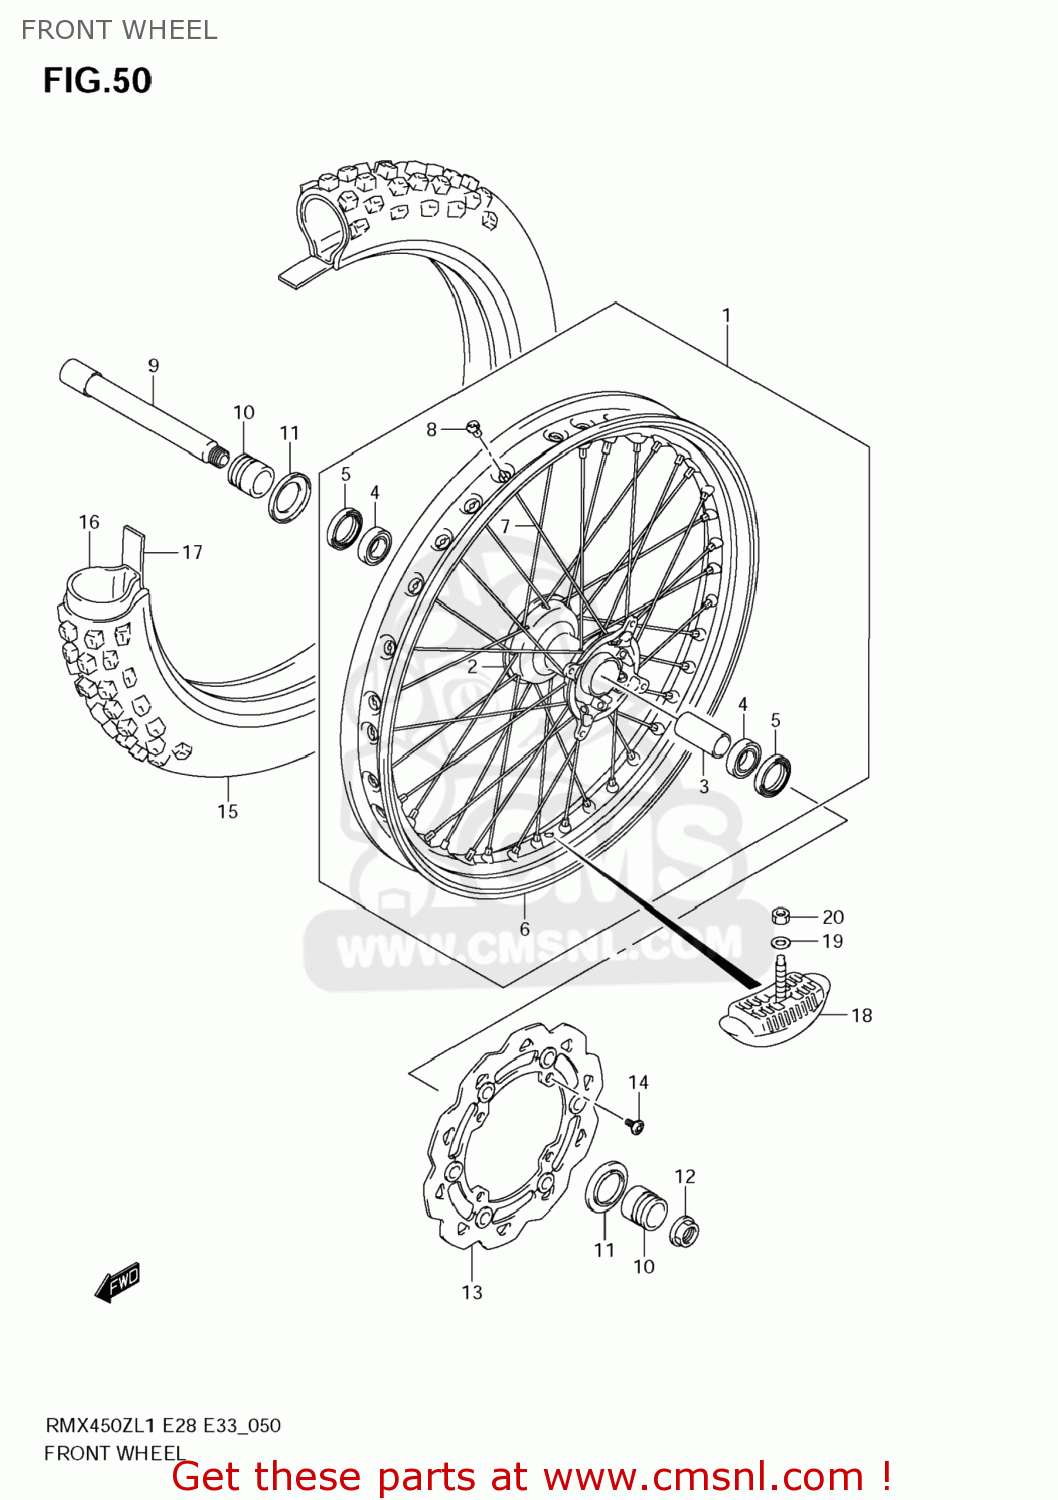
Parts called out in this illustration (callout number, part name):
1	WHEEL ASSY,FR
2	HUB,FR
3	SPACER,FR HUB BEARING
4	BEARING(22X39X9)
5	SEAL,OIL(30X40X7)
6	RIM,FR WHEEL
7	SPOKE,FR WHEEL
8	NIPPLE,FR WHEEL
9	AXLE,FR
10	SPACER,FR AXLE
11	COVER,FR AXLE SPACER
12	NUT
13	DISC,FR BRAKE
14	SCREW(6X13.5)
15	TIRE,FR(80/100 21)
16	TUBE ASSY,WHEEL INNER
17	PROTECTOR,WHL INR TUBE
18	STOPPER,BEAD
19	WASHER
20	NUT
